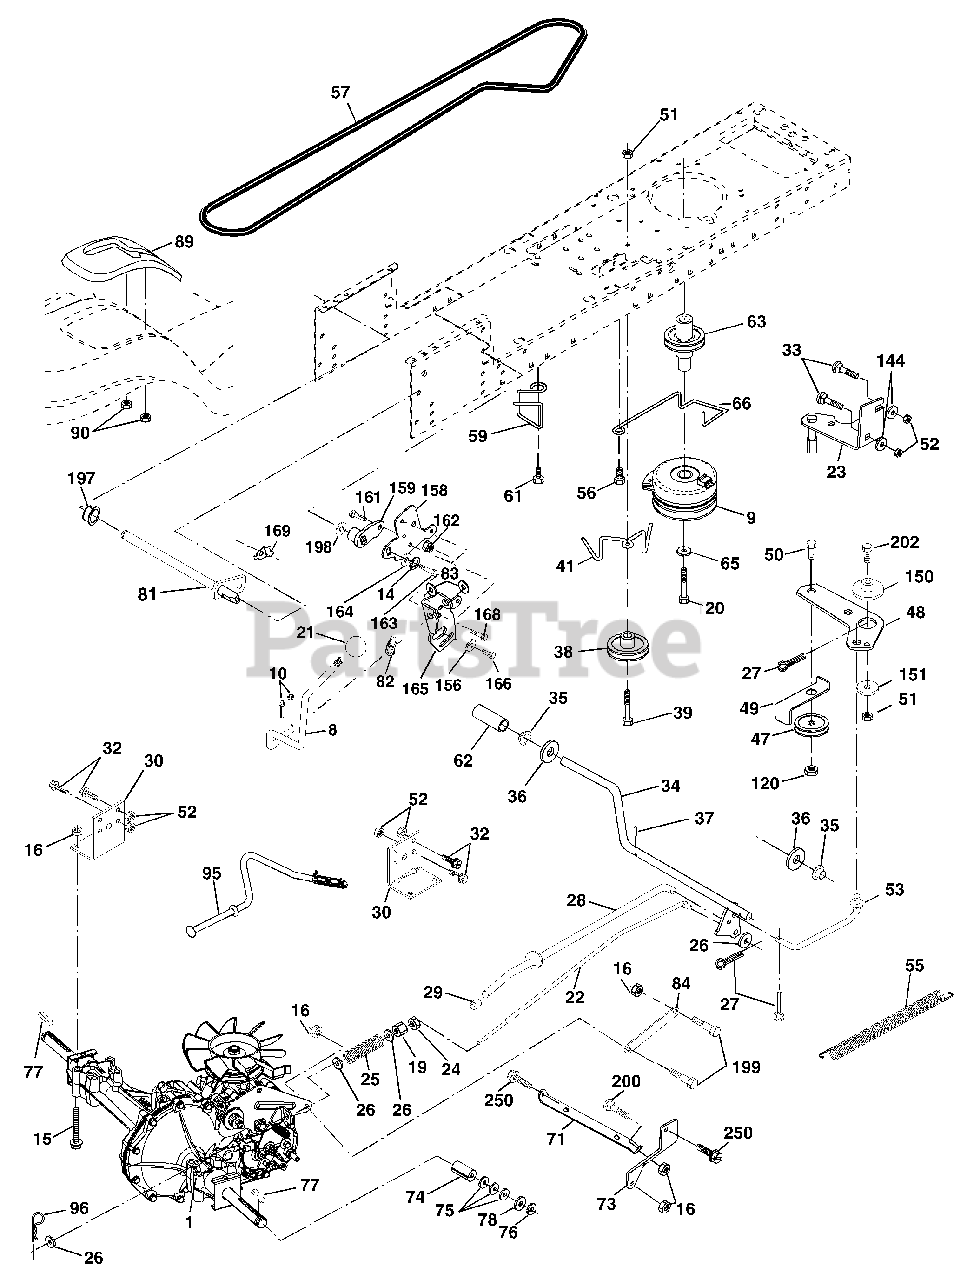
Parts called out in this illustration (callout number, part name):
8	Rod Shift Fender Adjust STLT
9	Clutch Elecric
10	Pin Cotter 1/8 x 1 CAD
14	Washer Lock Hvy Helical
15	Bolt Hex 5/16-18 Unc Flghd
16	Nut Lock Hex W/Ins. 5/16-18 Unc P
19	Nut Lock Hex W/Ins 3/8-16 Unc
20	Bolt, Hex 7/16-20 x 4-1/4
21	Knob Deluxe 1/2-13 UNC BLK/BLK
22	Rod, Brake Hydro
23	Bracket Asm Anti-Rot EVX
24	Nut Hex Jam 3/8-16 UNC
25	Spring, Brake Rod
26	Washer
27	Pin Cotter 1/8 x 3/4 CAD.
28	Rod, Parking Brake
29	Cap,Parking Brake
30	Bracket, Transaxle
32	Bolt Hex Hd 5/16-18 Unc x 3/4
33	Bolt Carriage 5/16-18unc x 3/4
34	Shaft, Foot Pedal
35	Bearing, Nylon
37	Pin, Roll
38	Pulley, Composite, Flat
39	Bolt, Fin, Hex 3/8-16 x 3
41	Keeper, Belt Idler
47	Pulley, Idler, V-Groove Plastic
48	Bellcrank Clutch Grnd Drv STL
49	Retainer, Belt Style Spring
50	Bolt Hex Hd 3/8-16 Unc x 1-1/2
52	Nut Crown Lock 5/16-18
53	Link, Clutch
55	Spring, Return, Clutch
56	Screw 3/8-16 x 1.0
57	V-Belt, Ground Drive
59	Keeper, Center Span
61	Screw
62	Cover, Pedal
63	Pulley, Egine
65	Washer Lock Hvy HLCL Spr 7/16
66	Keeper Belt Engine
71	Strap Torque Lh Hydro
73	Strap Torque Rh Hydro
74	Spacer, Axle
75	Washer 25/32 x 1-1/4 x 16 Ga.
77	Key, Square
78	Washer 25/32 x 1-5/8 x 16 Ga
81	Shaft Asm Cross Tapered
82	Spring Torsion T/A
83	Washer 17/32 x 3/4 x 16 Ga.
84	Link Transaxle
89	Console, Shift
90	Nut Self Thd 1/4
95	Control Asm. Bypass Hydro
96	Retainer Spring 1" Zinc/Cad
120	Nut Lock Flg 3/8-16
144	Washer 11/32 x 5/8 x 16 Ga.
150	Spacer Retainer
151	Washer 13/32 x 2 x 10 Ga.
156	Washer Srrted 5/16 ID x 1.125
158	Bracket Shift Mount
159	Hub Tapered Flange Shift Lt
161	Bolt Rdhd Sqnk 1/4-20 x 3/4 Gr 5
162	Nut Crownlock 1/4-20 Unc
163	Bolt Hex Fin 1/4-20 Unc x 1 Gr 5
164	Washer 5/8 x .281 x 10 Ga
165	Bracket Pivot Lever
166	Screw 5/16-18 x 5/8
168	Bolt Shoulder 5/16-18 x .561
169	Plate Fastening STLT/CRD
197	Nyliner Snap 5/8" ID
198	Washer Nyl 7/8 ID x .105 Hyd
199	Bolt Shoulder 5/16-18 Unc
200	Bolt Rdhd Sqnk 5/16-18 Unc x 1
202	Bolt 3/8-16 Unc x 1-3/4 Gr. 5
250	Screw 3/8-16 x .75
